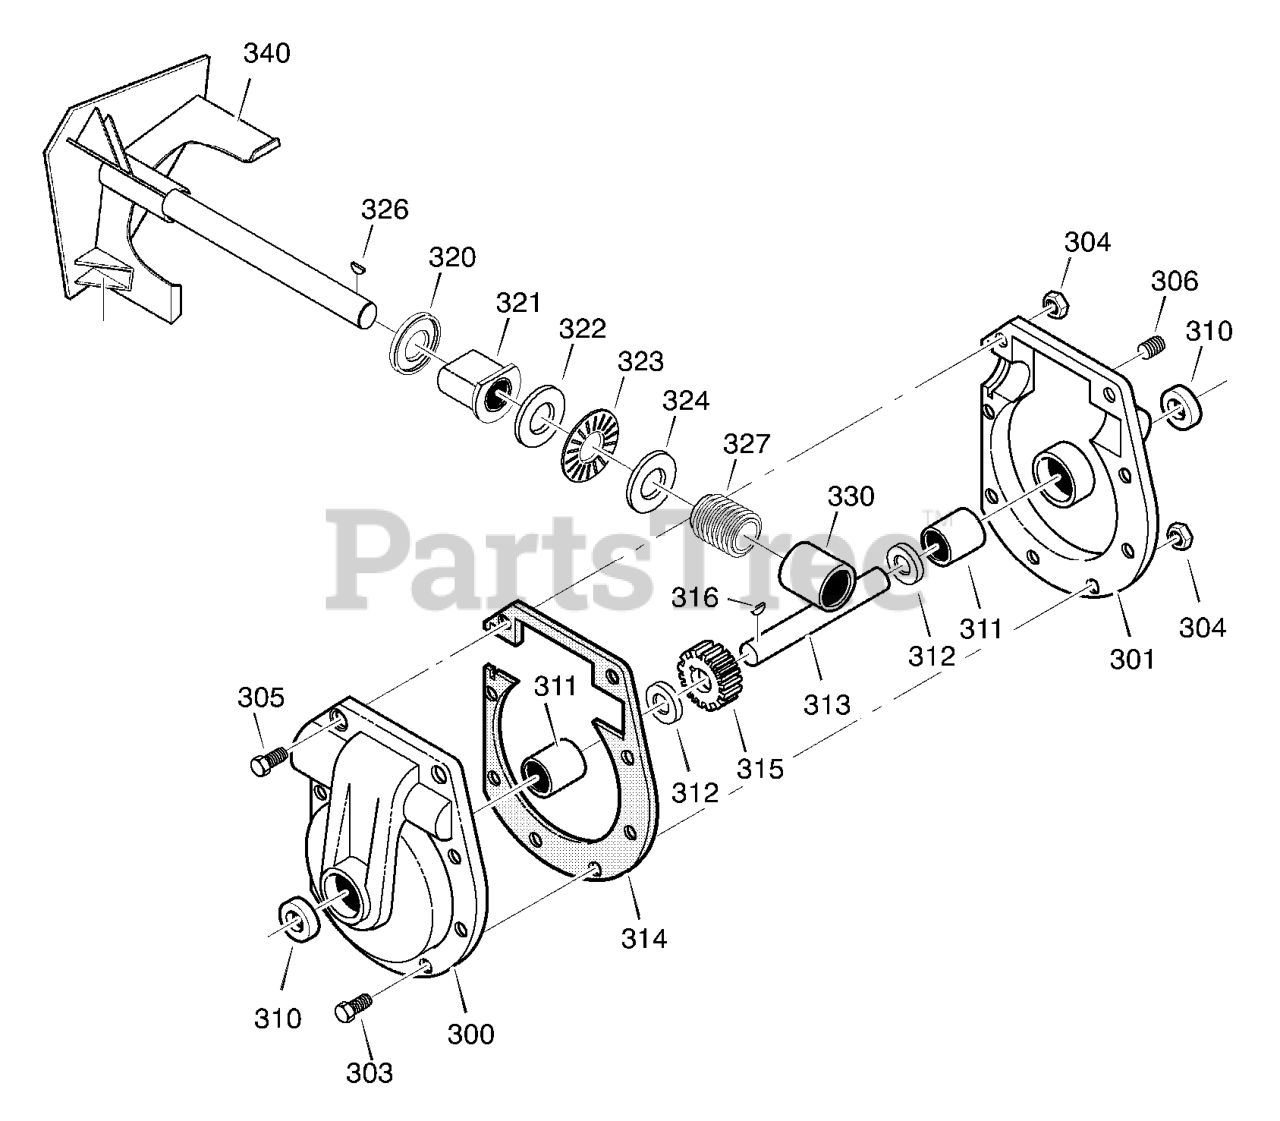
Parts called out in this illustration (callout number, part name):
300	CASE, GEAR, RH
301	CASE, GEAR, LH
303	SCREW,1/4-20X.75
304	NUT,1/4-20
305	NUT, 1/4-20 HEXKEPS
306	SCREW, 3/8-16 x 0.50
310	SEAL, OIL
311	BEARING, FL
312	WASHER, FLAT
313	SHAFT, AUGER OUTPUT
314	GASKET, GEAR BOX
315	WORM GEAR
316	KEY, WOODRUFF #61
320	BRNG, FL
321	SHAFT, AUGER INPUT
322	COLLAR, THRUST
323	PIN, SPRING
324	WASHER, FLAT
326	BRNG, FL
327	SEAL, OIL
330	BEARING
340	IMPELLER
